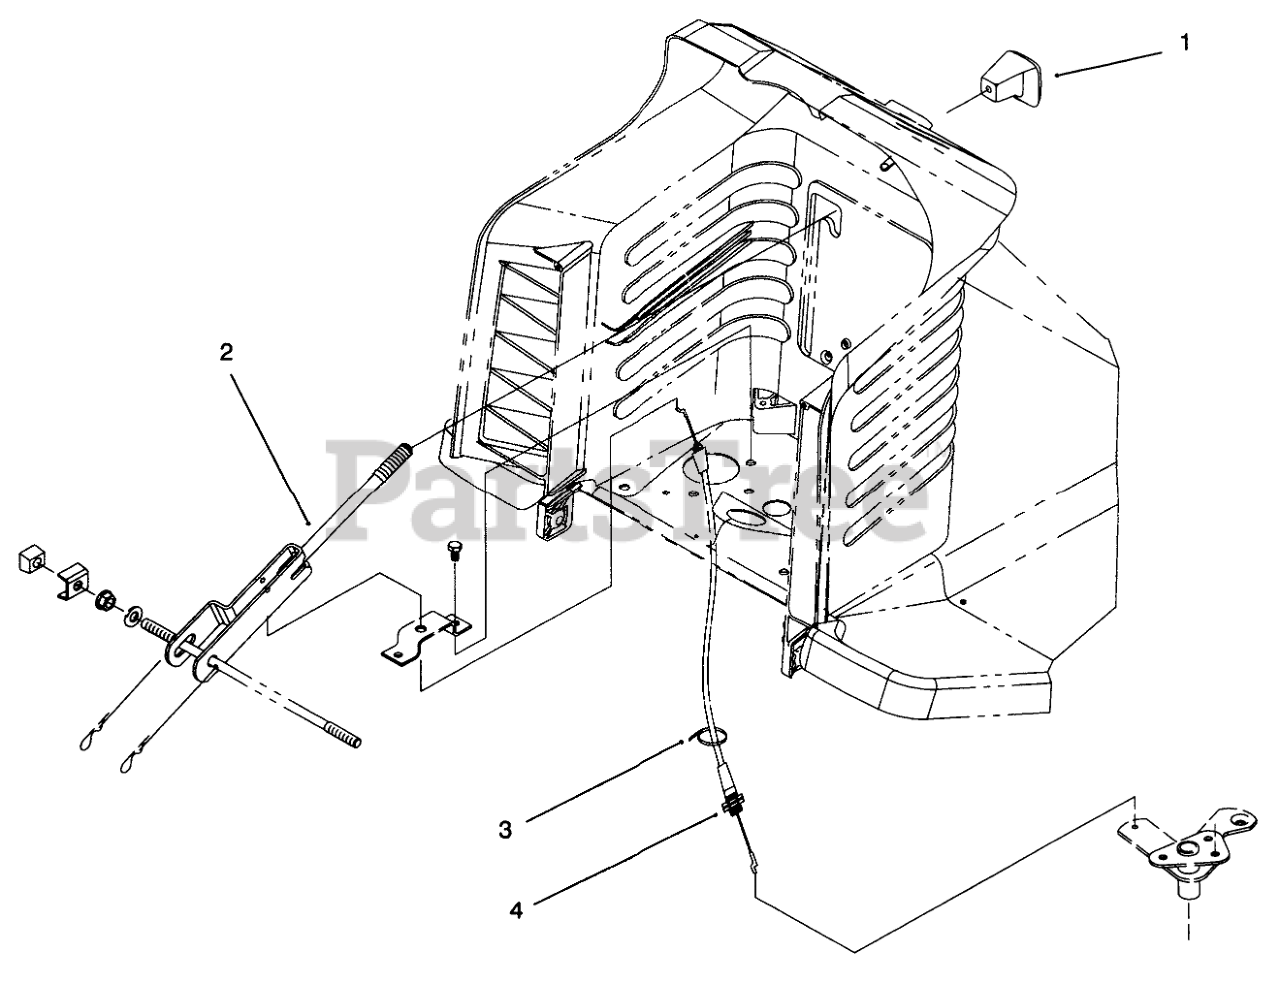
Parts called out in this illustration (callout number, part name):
1	KNOB-SHIFT
2	Lever-Deck Engage
3	TIE-CABLE
4	Cable-Deck Engage
